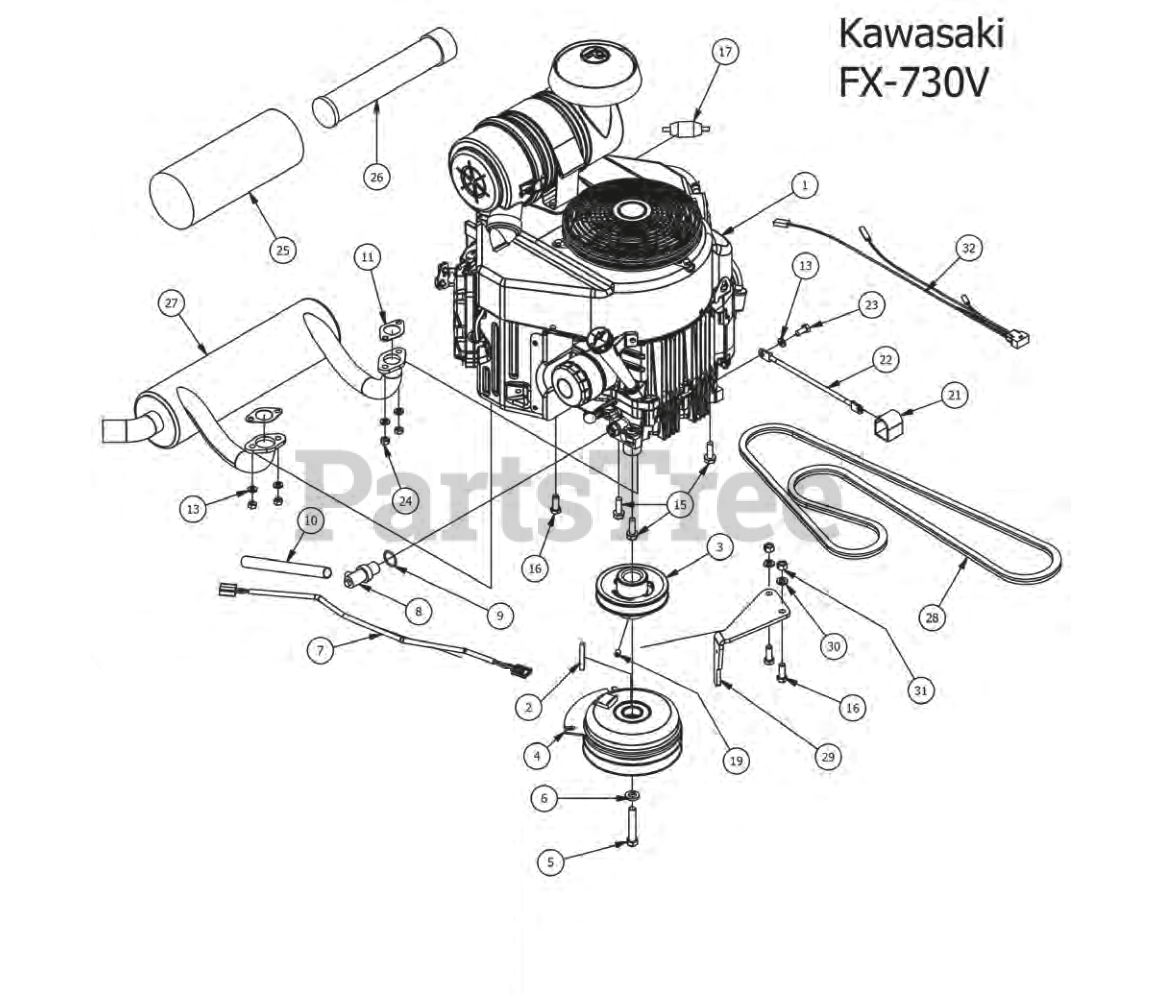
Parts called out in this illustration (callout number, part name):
2	1/4 x 2 Square key Stock
3	4 3/4 Motor Pulley
4	Clutch Assembly
5	7/16" x 2 1/2" Hex Bolt
6	7/16" Lock Washer
7	Clutch Pigtail
10	1/2 Clear Braded Hose Priced/Foot
11	Exhaust gasket
13	5/16" Lock Washer
15	3/8 x 1 1/8 bolt
16	3/8" x 1" Hex Bolt
17	Universal inline Fuel Filter
19	5/16 Set Screw
21	Black Boot For ground cable
22	Ground Cable
23	M8x1.20x20MM Hex head bolt
24	M8-1.25 Zinc Nut
25	Canister Air Filter- Outer
26	Canister Air Filter- Inner
27	Exhaust Kawasaki
29	PTO Engager Holder
30	3/8" Lock Washer
31	3/8" Hex Nut
32	Harness Adaptor Outlaw FX (All)
